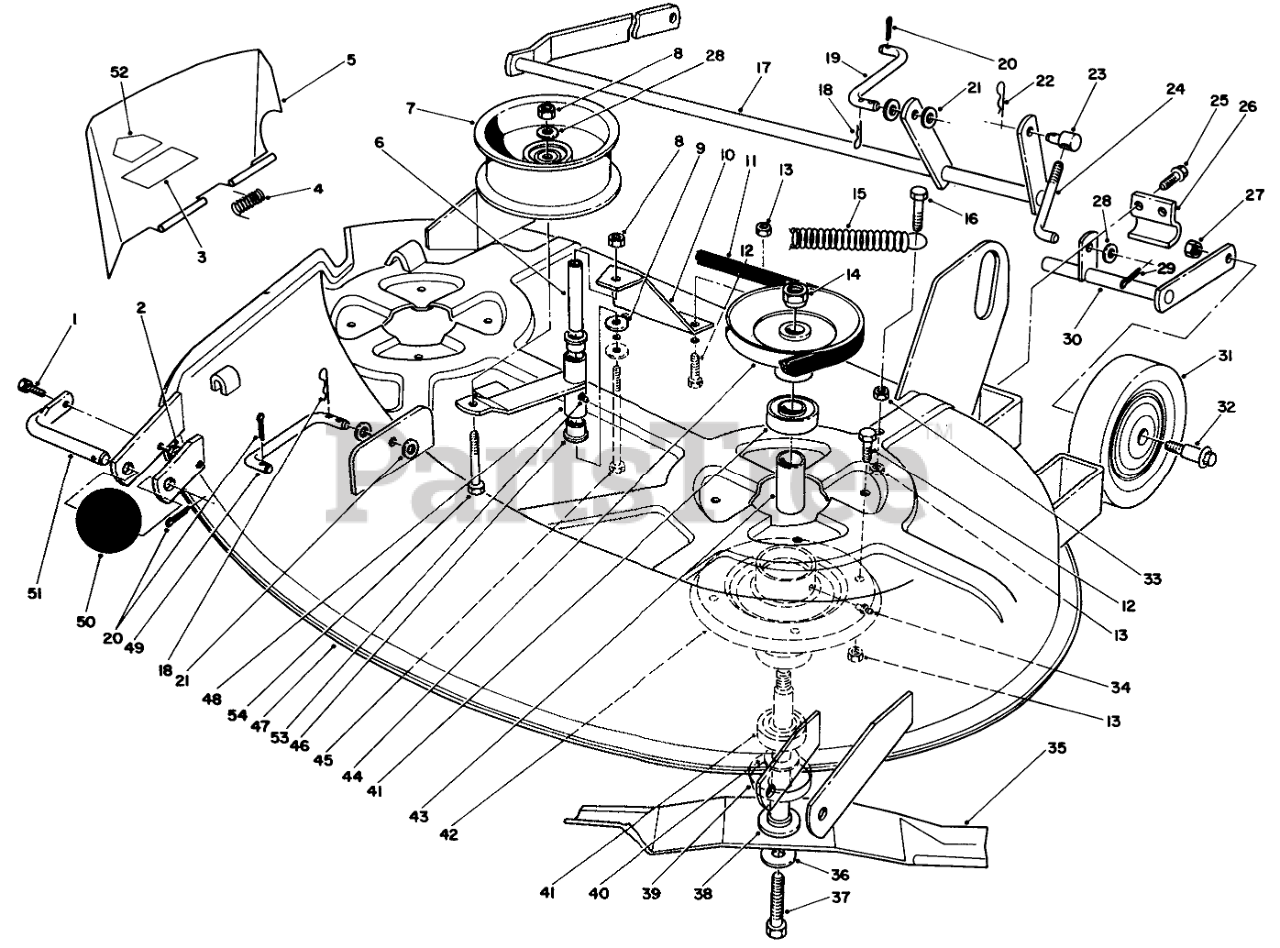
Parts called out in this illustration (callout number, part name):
1	Bolt
2	Nut
3	DECAL-DANGER, THROWN OBJECT
4	SPRING-TORSION
5	Deflector
6	SPACER
7	Pulley-Idler
8	NUT
9	WASHER
10	BRACE R
11	V-Belt
12	Bolt
13	Nut
14	Nut
15	SPRING-EXTENSION
16	Bolt
17	Shaft-R.H.
18	Hairpin
19	LINK-REAR
20	Cotter Pin
21	Washer
22	Hairpin
23	TRUNNION
24	ROD-LIFT
25	Bolt
26	Camp
27	Nut
28	Washer
29	Cotter Pin
30	Shaft-L.H.
31	WHEEL
32	BOLT-SHOULDER
33	Nut
34	ZERK FITTING
35	Blade
36	WASHER
37	SCREW-HH
38	SHAFT-SPINDLE
39	SHIELD-BEARING
40	SPACER-HARDNED
41	BEARING-BALL
42	Housing-Spindle
43	SPACER
44	Pulley-Spindle
45	Bolt 3/8-16 x 4
46	BUSHING
47	Deck-Cutting Unit
48	Arm-Idler
49	LINK-FRONT
50	ROLLER
51	SHAFT-ROLLER
52	DECAL-DANGER
53	FITTING-GREASE
54	Bolt
